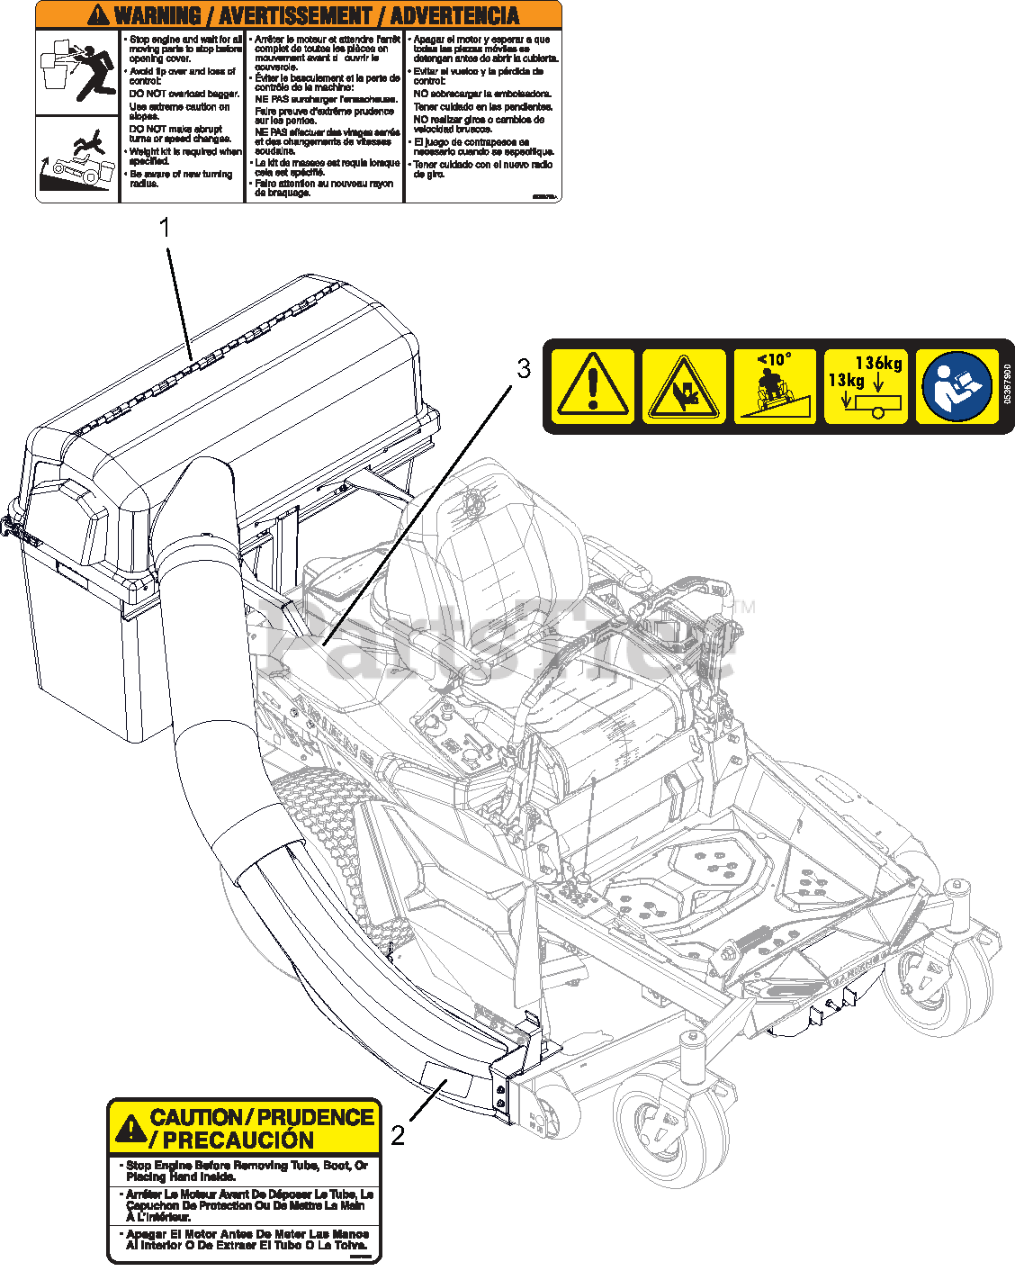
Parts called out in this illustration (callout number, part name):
1	DECAL, BAGGER COVER
2	DECAL-BOOT CAUTION
3	DECAL, TRAILER HITCH
